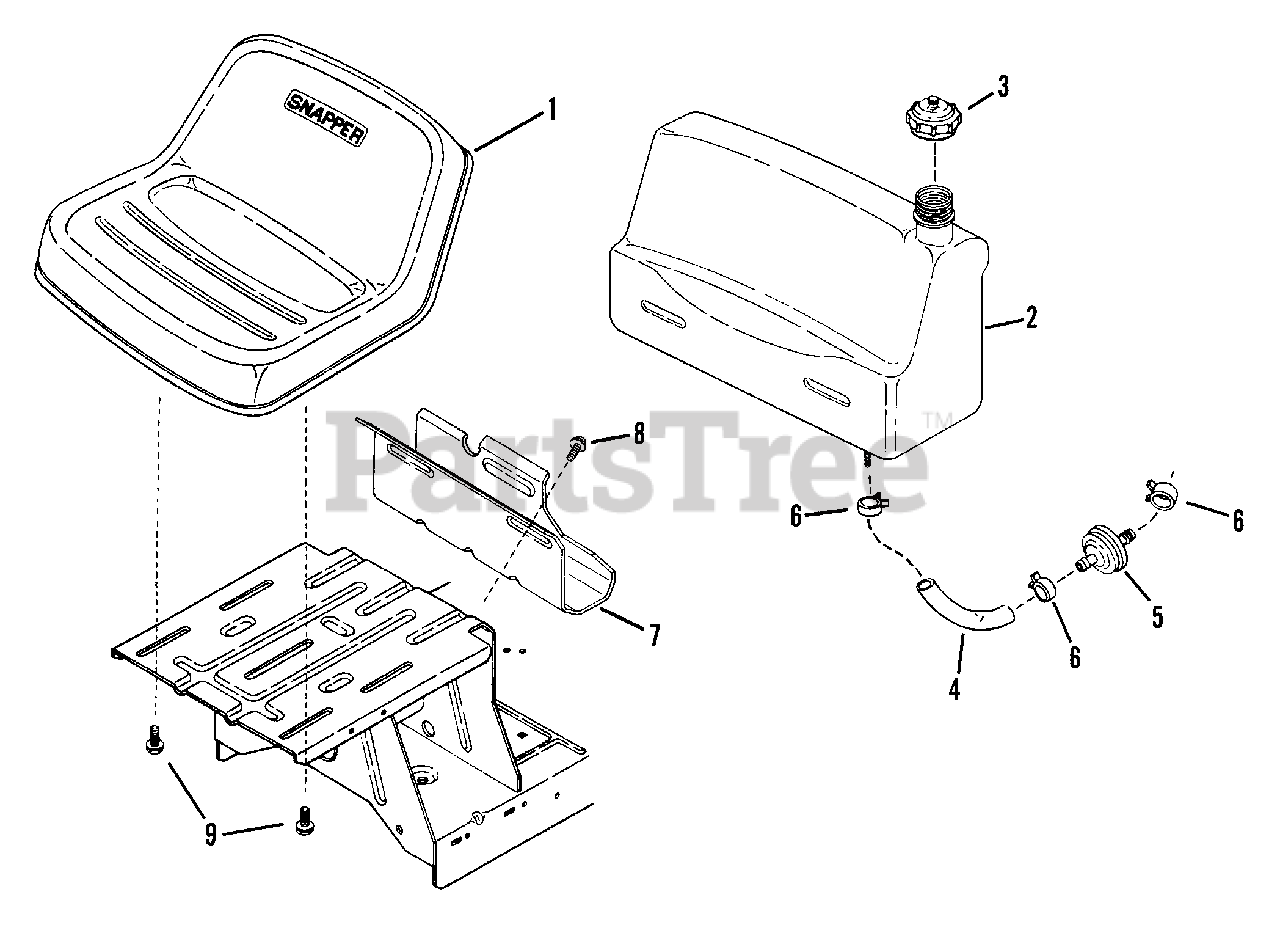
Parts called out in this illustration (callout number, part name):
1	SEAT, Operator
2	ASSEMBLY, Fuel Tank
3	CAP, Fuel Tank
4	HOSE, Fuel (7" Long)
5	FILTER, Fuel (In-Line)
6	CLAMP, Fuel Line
7	BRACKET, Fuel Tank (Rear)
8	SCREW, 5/16-18 x 5/8" Self-Tapping
9	BOLT, 5/16-18 x 1/2" Hex Flange Lock
